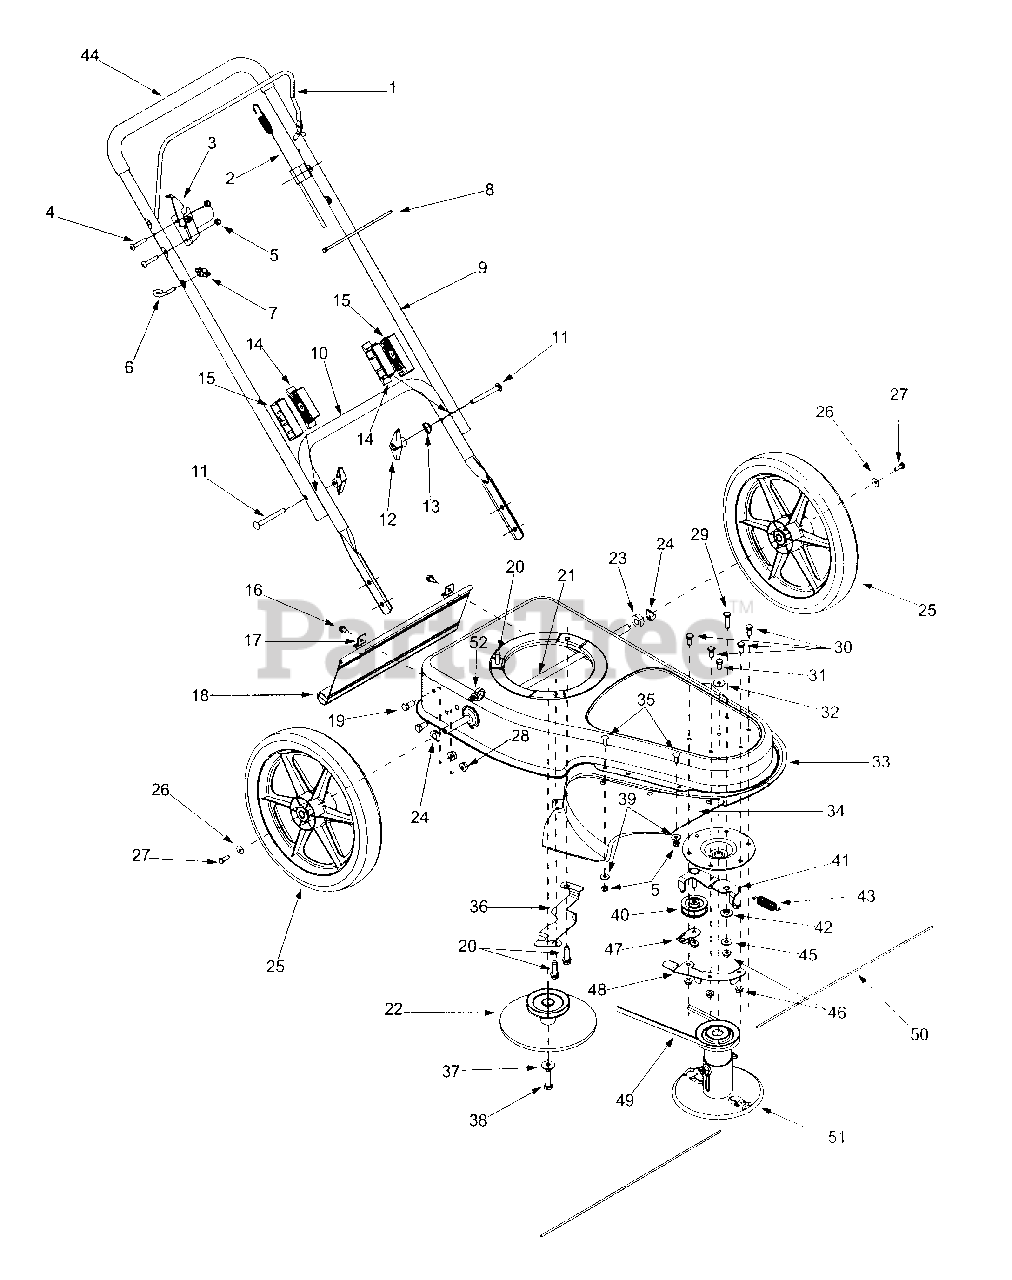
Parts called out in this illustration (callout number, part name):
1	Control Lever
2	Engagement Cable
3	Control Lock Bracket
4	Machine Screw 1/4-20 x 1.50
5	Hex Lock Nut 1/4-20
6	Eye Bolt 1/4-20
7	Wing Nut
8	Cable Tie
9	Upper Handle
10	Lower Handle
11	Carriage Screw 5/16-18 x 3.0
12	Wing Nut
13	Shoulder Washer.320 ID x .93 OD
14	Lower Handle Connector
15	Upper Handle Connector
16	Hex Washer Screw 1/4-14 x .625
17	Trail Shield Clip
18	Trail Shield
19	Hex Cap Screw 3/8-16 x .750
20	Hex Washer Screw 3/8-16 x 1.25
21	Trimmer Axle
22	Flywheel Pulley
23	Spacer .51 ID x 1.0 OD
24	Spacer Washer .501 ID x 1.0 OD
25	Wheel Assembly
26	Bell Washer .265 ID x .75 OD
27	Hex Cap Screw 1/4-20 x .75
28	Flange Lock Nut 3/8-16
29	Screw 5/16-18 x 1.25
30	Screw 5/16-18 x .75
31	Hex Cap Screw 5/16-24 x .625
32	Bell Washer .325 ID x .930 OD
35	Hex Carriage Screw 1/4-20 x .75
38	Hex Cap Screw 3/8-24 x 1.50
39	Flat Washer .28 ID x .74 OD
40	Idler Pulley
41	Idler Bracket Assembly
42	Idler Spacer
43	Extension Spring .50 Dia x 1.88 Lg
44	Handle Grip
45	Flat Washer
46	Flange Lock Nut 5/16-18
49	V-Belt
50	Trimmer Line .155 Dia.
51	Spindle Assembly, includes 782-0143
51	Hex Lock Nut 1/4-20
52	Cable Retainer Clip
